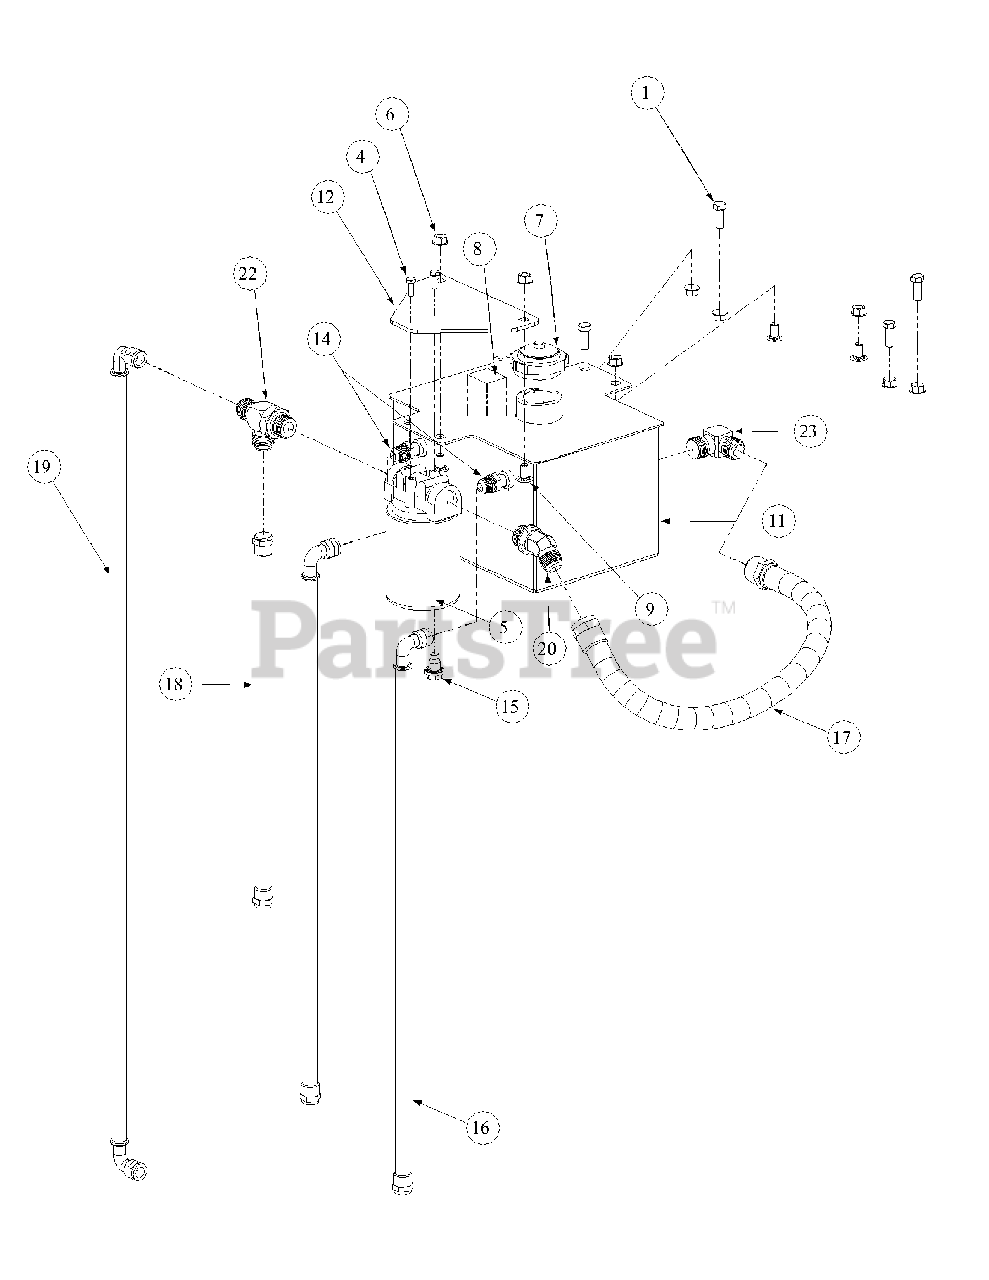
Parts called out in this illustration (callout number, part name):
1	Hex Cap Screw, 3/8-16, 1
3	Protective Hose Cover
4	Hex Cap Screw, 1/4-20, .75
5	Filter Head 3/4
6	Hex Nut Flange Lock, 3/8-16
7	Cap, Hydro Oil Tank
8	Decal Oil Only 20W50
9	Carriage Bolt, 3/8-16 x .75 LG.
11	Hydraulic Tank Assembly
12	Mounting Plate Oil Filter
14	Fitting, 3/8 NPT, 1/2 Flare
15	Oil Pan Drain w/ Seal and Plug
16	Gearbox to Tank Hose Assembly
17	Tank to Filter Hose Assembly
18	Filter to Left Hand Pump Hose Assembly
19	Filter to Right Hand Pump Hose Assembly
20	Connector, 3/4 x3/4
22	Fitting Tee, 3/4 x 1/2 x 1/2
23	Fitting Elbow, 1/2 x 1/2
